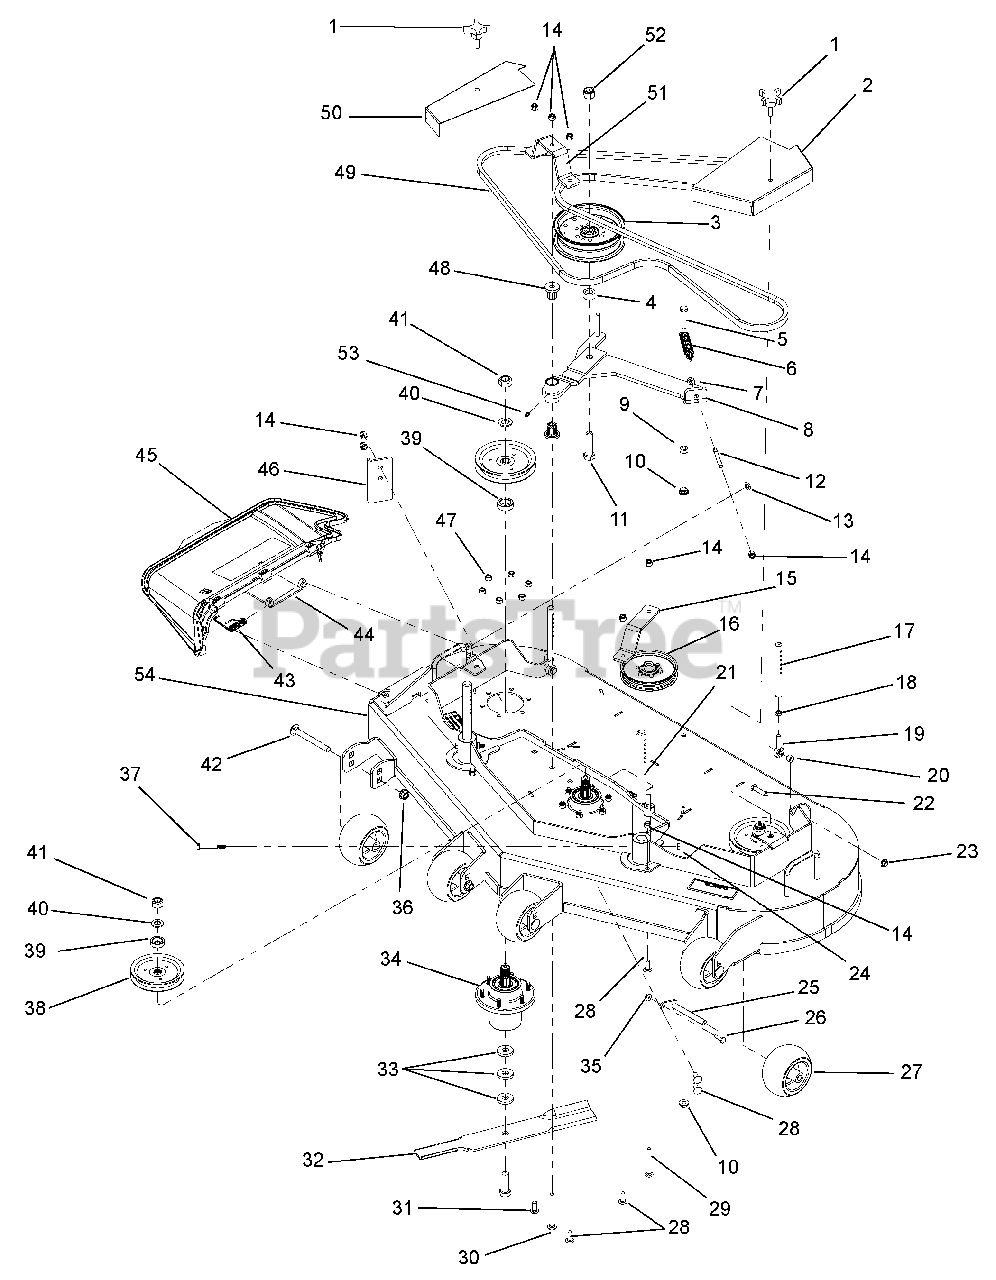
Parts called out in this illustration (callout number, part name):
1	KNOB, STAR 3/8-16 X 1.00
2	SHIELD, LH SPINDLE 52 FLWLK (988148)
3	PULLEY, FLAT 6.00 X .635 W/BRG
4	BUSHING, .688 X 1.13 X .55
5	BOLT, 7/16-14 X 2.00 HEX 5 Y
6	SPRING, EXT .875 X .125 X 4.25 Y
7	LOCKNUT, 3/8-16 WHIZ Y
8	WLDT, IDLER ARM 48/52 FLOAT WALK
9	NUT, 7/16-14 STD HEX GR5 Y
10	LOCKNUT, 7/16-14 WHIZ Y
11	BOLT, 5/8-11 X 2.50 HEX 5 Y
12	ROD, THREADED ADJUSTMENT
13	RETAINER #
14	LOCKNUT, 3/8-16 NYLOC Y
15	STRAP, IDLER 52/48 WALK
16	PULLEY, FLAT 5.00X.375 W/BRG
17	ROD, REAR HOC
18	NUT, JAM .375-24 YWZC REV
19	ROD, END 3/8 RH REV
20	BSHG - SLV REV
21	ROD, FRONT HOC
22	BOLT, 3/8-16 X 1.50 HEX 5 Y
23	NUT, LK-TOP-FLG .375-16 YWZC REV
24	LOCKNUT, 5/16-18 WHIZ Y
25	PIVOT, RETAINER WELD
26	BOLT, 1/4-20 X 1.00 SQU SN Y
27	WHEEL, GAGE
28	BOLT, 3/8-16 X 1.00 CRG 5 SN Y
29	BLT, RDHD SQNK .38-16 X 3.0 GR5YZ REV
30	BLT, RDHD SQNK .375-16 X 3.75 YWZC
31	BOLT, 5/8-11 X 2.00 HEX 8 Y
32	BLADE, 18.000 X .80 LIFT (988148)
33	WASHER, BLADE
34	ASSY, SPINDLE HOUSING
35	NUT, 1/4" FLANGE PREVAILING TOR
36	LOCKNUT 1/2 W/FLANGE
37	BOLT, 5/16-18 X 2.50 HEX 8 Y
38	PULLEY, SPLINE SPINDLE SHFLWLK
39	SPACER, 1.500 X 1.000 X .510 Y
40	WASHER, .75 X 1.3125X .113
41	LOCKNUT, 3/4-16 CROWN C
42	BOLT, 1/2-13 X 4.50 CRG 5 Y
43	SPRING, DISCHARGE CHUTE
44	BRACKET, CHUTE SUPPORT 48" DECK
45	CHUTE DISCHARGE ASST #
46	PLATE, EXTENDER 48" HYDRO
47	NUT, 3/8-16 STD HEX GR5 Y
48	BRG, FLG M10 X M25 X M27 FLUTED
49	BELT, HB 131.0 EL AMD (988148)
50	SHIELD, RH SPINDLE 52 FLWLK (988148)
51	STRAP, IDLER 52 FLOAT WALK (988148)
52	NUT, LK-NYL .625-11 YWZC REV
53	FTG, 1/4-28 STRGT GREASE ZERK
54	ASSY, 52" FLOAT DECK W/DECALS (988148)
